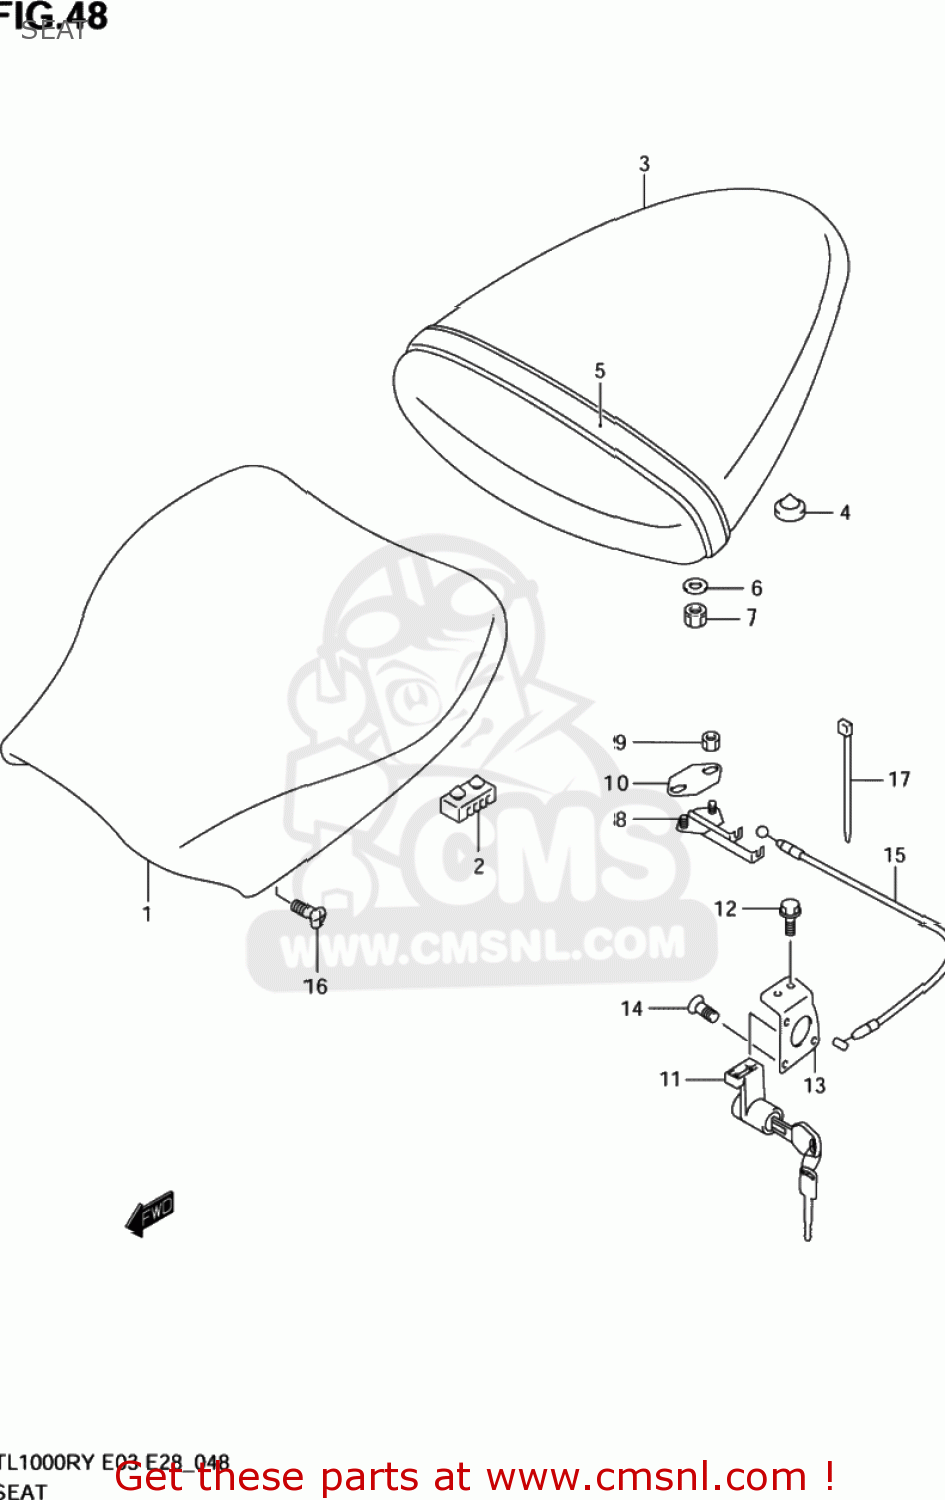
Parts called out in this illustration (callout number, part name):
1	SEAT ASSY
2	CUSHION,SEAT(40X20X15)
3	SEAT ASSY,PILLION
4	CUSHION(11.5X22X20)
5	BAND ASSY,PILLION SEAT
6	WASHER(6.5X20X1.6)
7	NUT
8	BRACKET,SEAT SUPPORT
9	NUT
10	PLATE,SEAT SUPPORT BRKT
11	LOCK SET,SEAT
12	BOLT
13	BRACKET,SEAT LOCK
14	SCREW
15	CABLE,SEAT LOCK
16	BOLT(6X18)
17	CLAMP(L:145)
